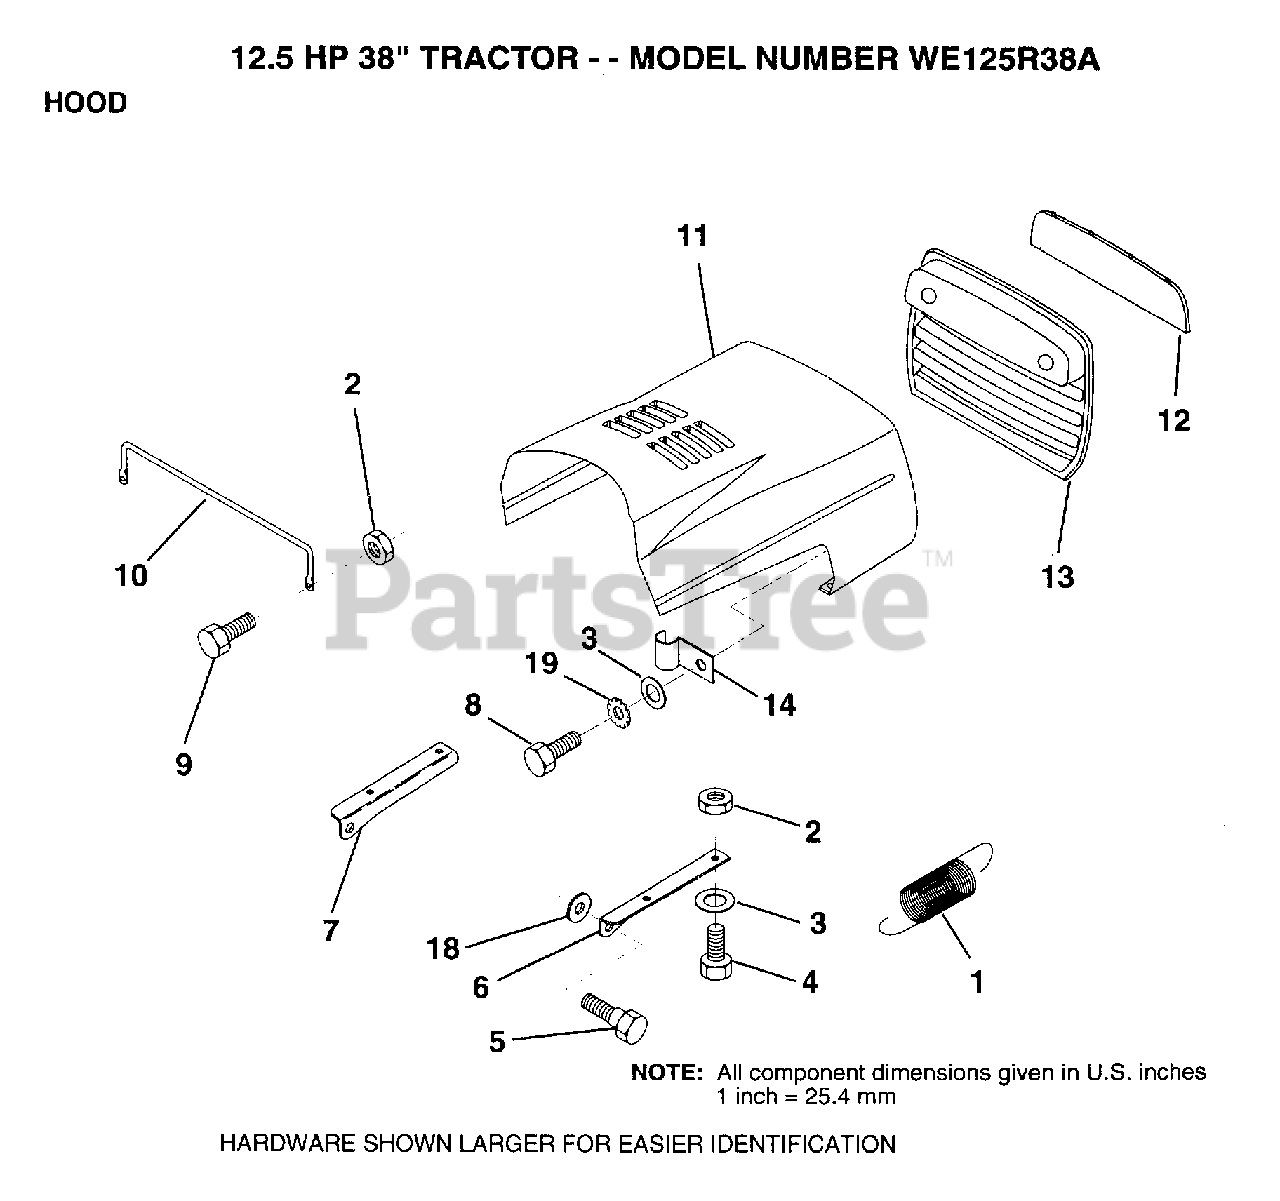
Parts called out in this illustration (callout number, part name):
1	EXT SPRING
2	NUT
3	WASHER
4	BOLT
6	BRKT HOOD RH
7	BRKT HOOD LH
10	"BRACE,HOOD"
11	HOOD
12	LENS
13	GRILL
14	CLIP T
18	WASHER
19	LOCKWASHER GT
